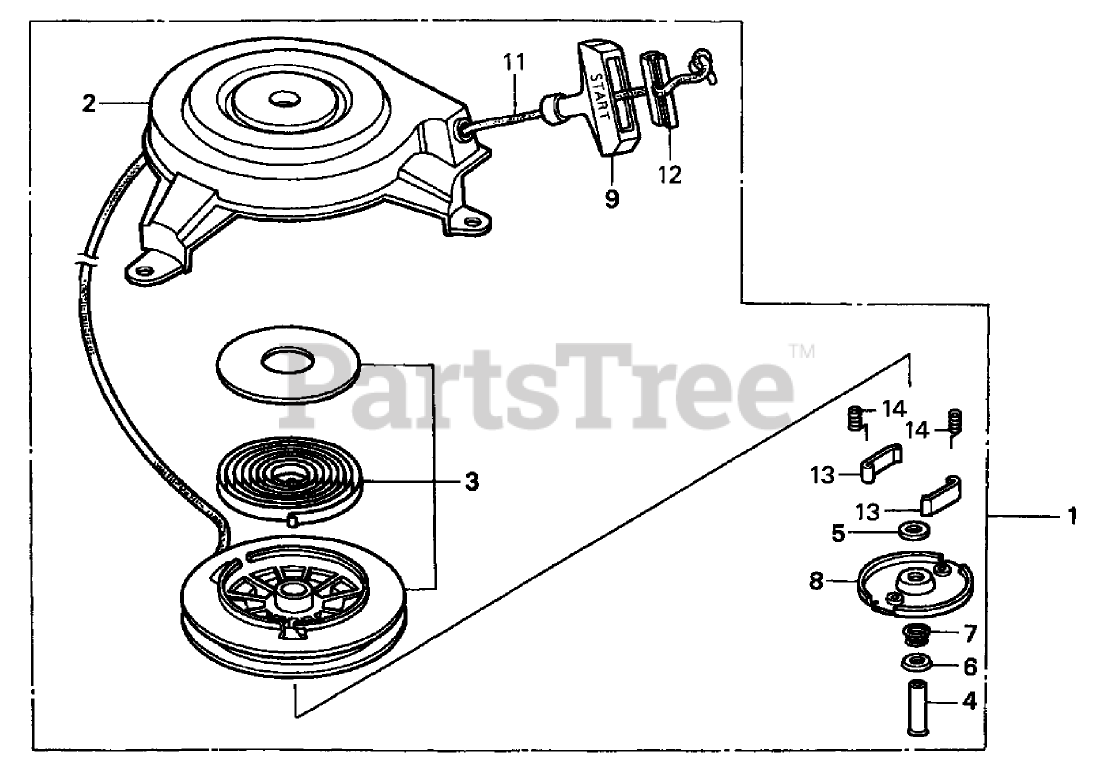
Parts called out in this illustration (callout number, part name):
1	RECOIL STARTER ASM
2	HOUSING ASM
3	PULLEY AND SPRING ASM
4	Pin-Center
5	Plate A-Friction
6	PLATE B-FRICTION
7	Spring-Friction
8	Retainer
9	Handle
11	ROPE-STARTER, RECOIL
12	Handle-Reinforcement
13	Ratchet-Starter
14	Spring-Dog
